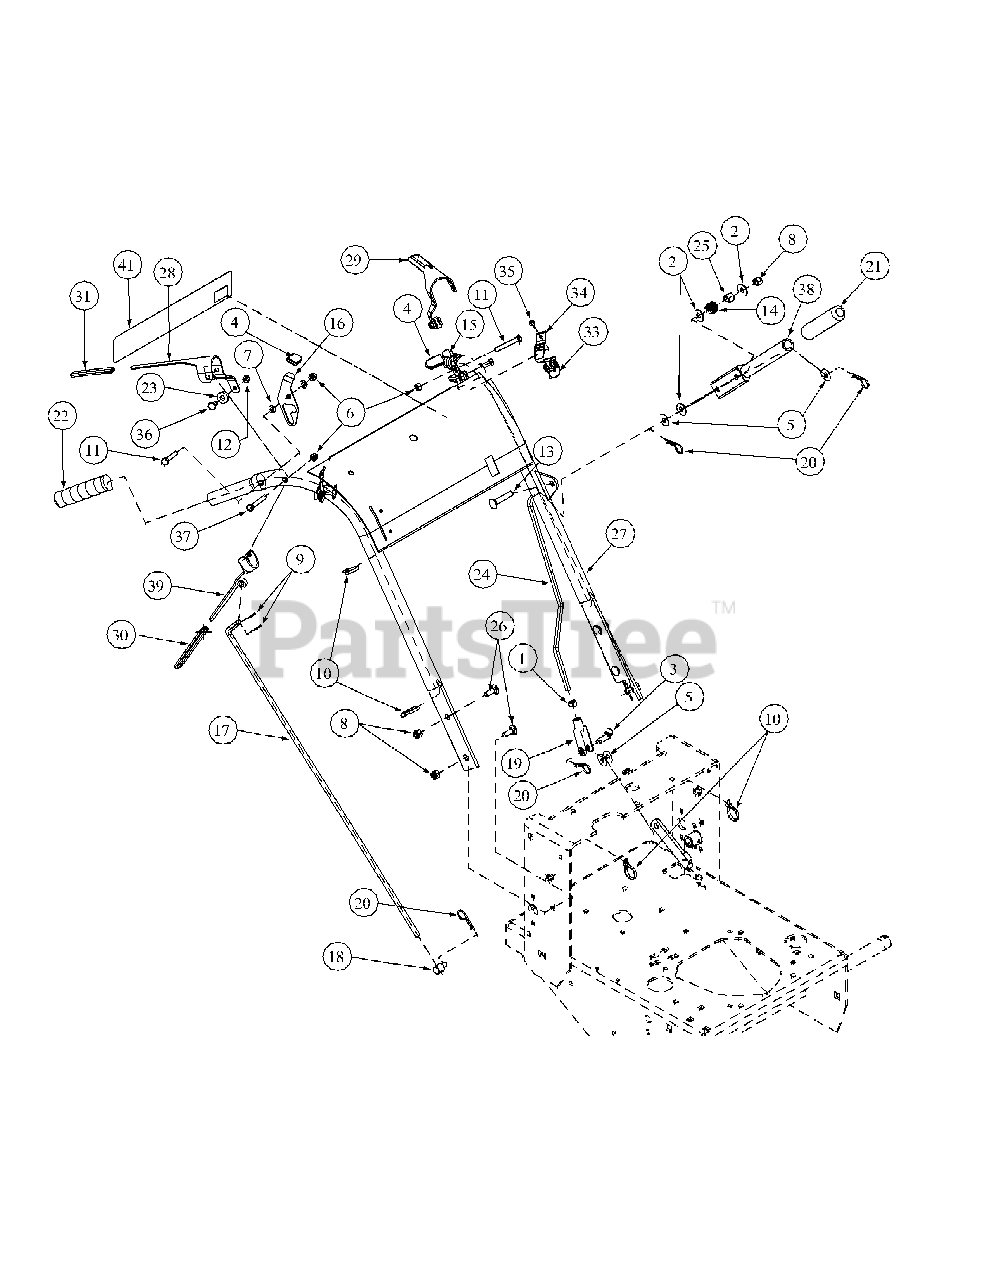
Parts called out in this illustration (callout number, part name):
1	Hex Nut, 3/8-16
2	Flat Washer, 3/8 Zinc
3	Clevis Pin, 3/8 x 1-1/8 Zinc
4	Grip, Neutral Latch, 1.25"
5	Flat Washer, 3/8 Zinc
6	Nylock Nut, 5/16-18
7	Flat Washer, 5/16 Zinc
8	Lock Nut, Nylon Insert, 3/8-16
9	Cotter Pin, 3/32 x 3/4, Zinc
10	Cable Tie, 3/16 x .05 x 7.4
11	Hex Cap Screw, 5/16-18 x 2
12	Lock Nut, Nylon Insert
13	Carriage Bolt, 3/8-16 x 2
14	Spring, .850 OD x 1
15	Neutral Latch, Left Hand
16	Neutral Latch, Right Hand
17	Steering Control Rod
18	Joint Swivel
19	Yoke, 3/8-16 Female
20	Hair Pin 3/8-1/2
21	Handle Grip, Black, 1"
22	Plastic Handle Grip, Black, 4-5/8
23	Control Rod, Hydro Spacer
24	Hydro Blade Clutch Rod Base
25	Spring Sleeve
26	Carriage Bolt, 3/8-16 x 2
27	Handle Assembly
28	Operator Presence Control RH
29	Operator Presence Control LH
30	Control Sleeve, Black
31	Operator Control Sleeve, Yellow
32	Harness Assembly Adapter
33	Switch Mounting Snap
34	Operator Presence Return Spring
35	Hex Index Washer Screw, 0.500
36	Shoulder Screw, .38 x .412, 1/4-28
37	Hex Cap Screw, 5/16-18, 2.00
38	Blade Clutch Lever
39	Lever Assembly Control
41	Label Commercial Mower Instruction
